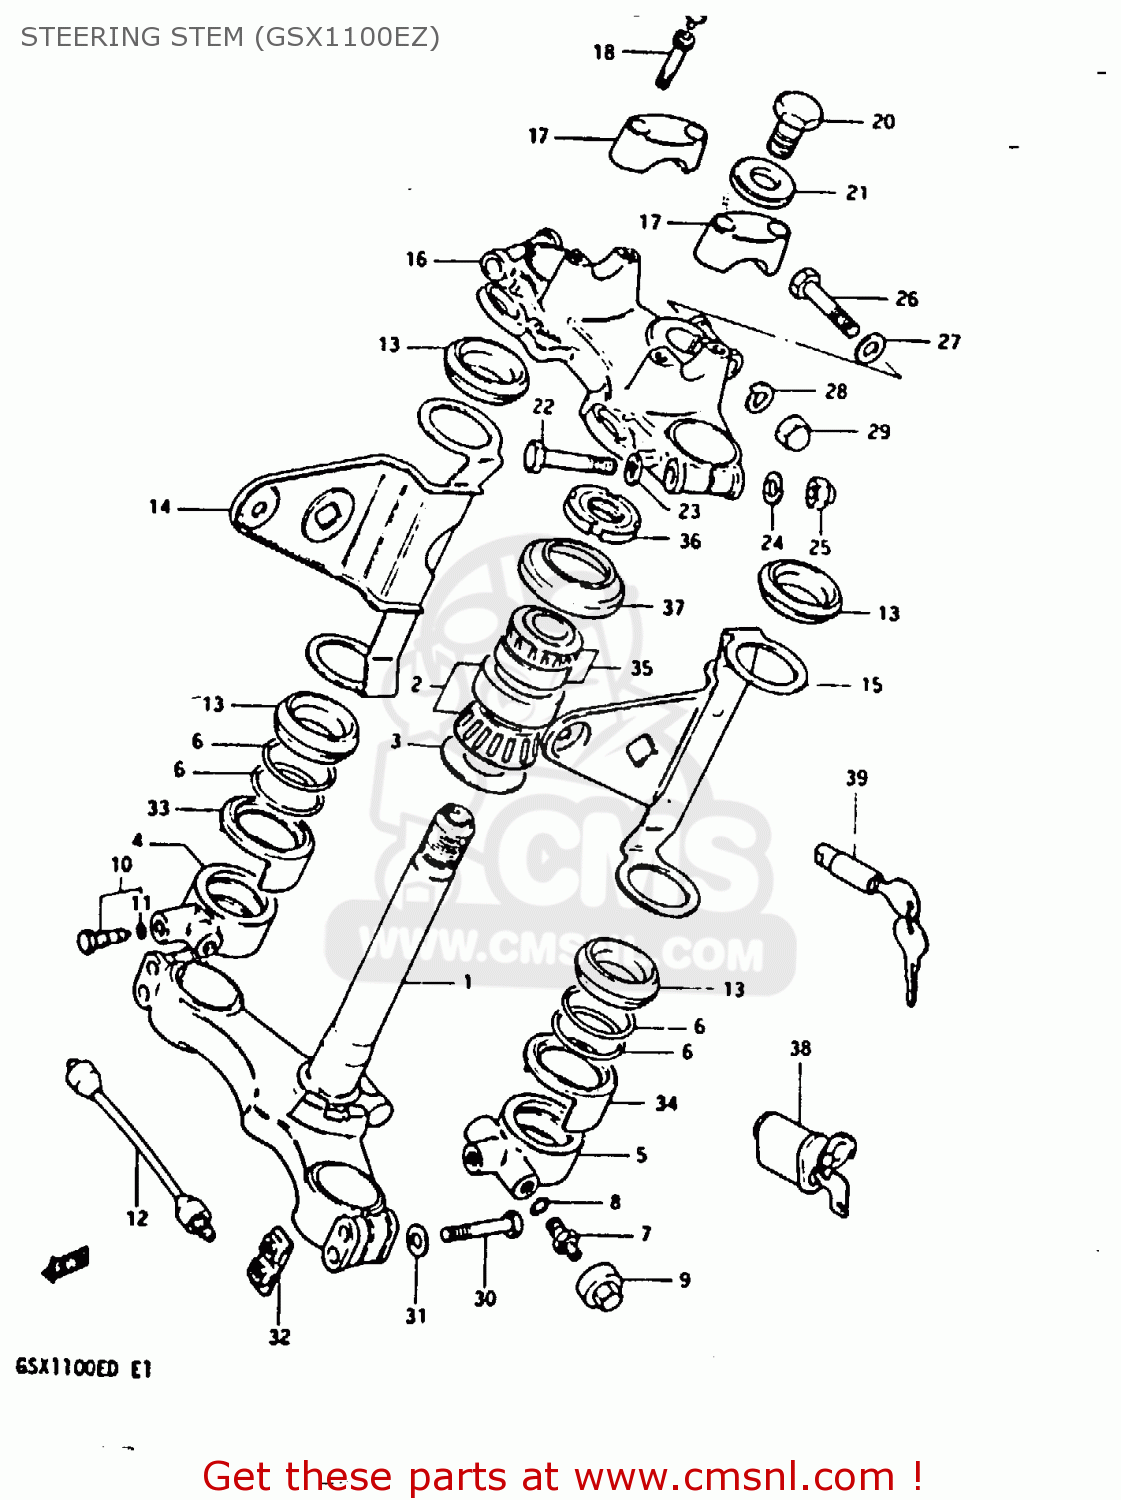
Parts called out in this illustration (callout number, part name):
1	STEM,STEERING
2	BEARING
3	WASHER,THRUST
4	JOINT,AIR,RIGHT
5	BRACKET,FORK CONNECTING
6	O RING
7	VALVE
8	O RING
9	CAP,VALVE
10	VALVE,STOP
11	O RING
12	HOSE,FORK CONNECTING
13	CUSHION,HEADLAMP BRACKET
14	BRACKET,HEADLAMP,RIGHT
15	BRACKET,HEADLAMP,LEFT
16	HEAD,STEERING STEM
17	HOLDER,HANDLEBAR
18	BOLT
19	CAP(OD:14.5)
20	NUT,STEM HEAD
21	WASHER,STEERING STEM B
22	BOLT 10X55
23	WASHER
24	LOCK WASHER
25	NUT 10MM
26	BOLT 8X50
27	WASHER
28	LOCK WASHER
29	NUT,M8X1.25X12
30	BOLT 8X55
31	WASHER
32	NUT,FR FORK INNER TUBE
33	COVER,FORK BRACKET,RIGHT
34	COVER,FORK BRACKET,LEFT
35	TAPER,ROLLER BEARING
36	NUT,STEERING STEM
37	DUST SEAL,STEERING UPR
